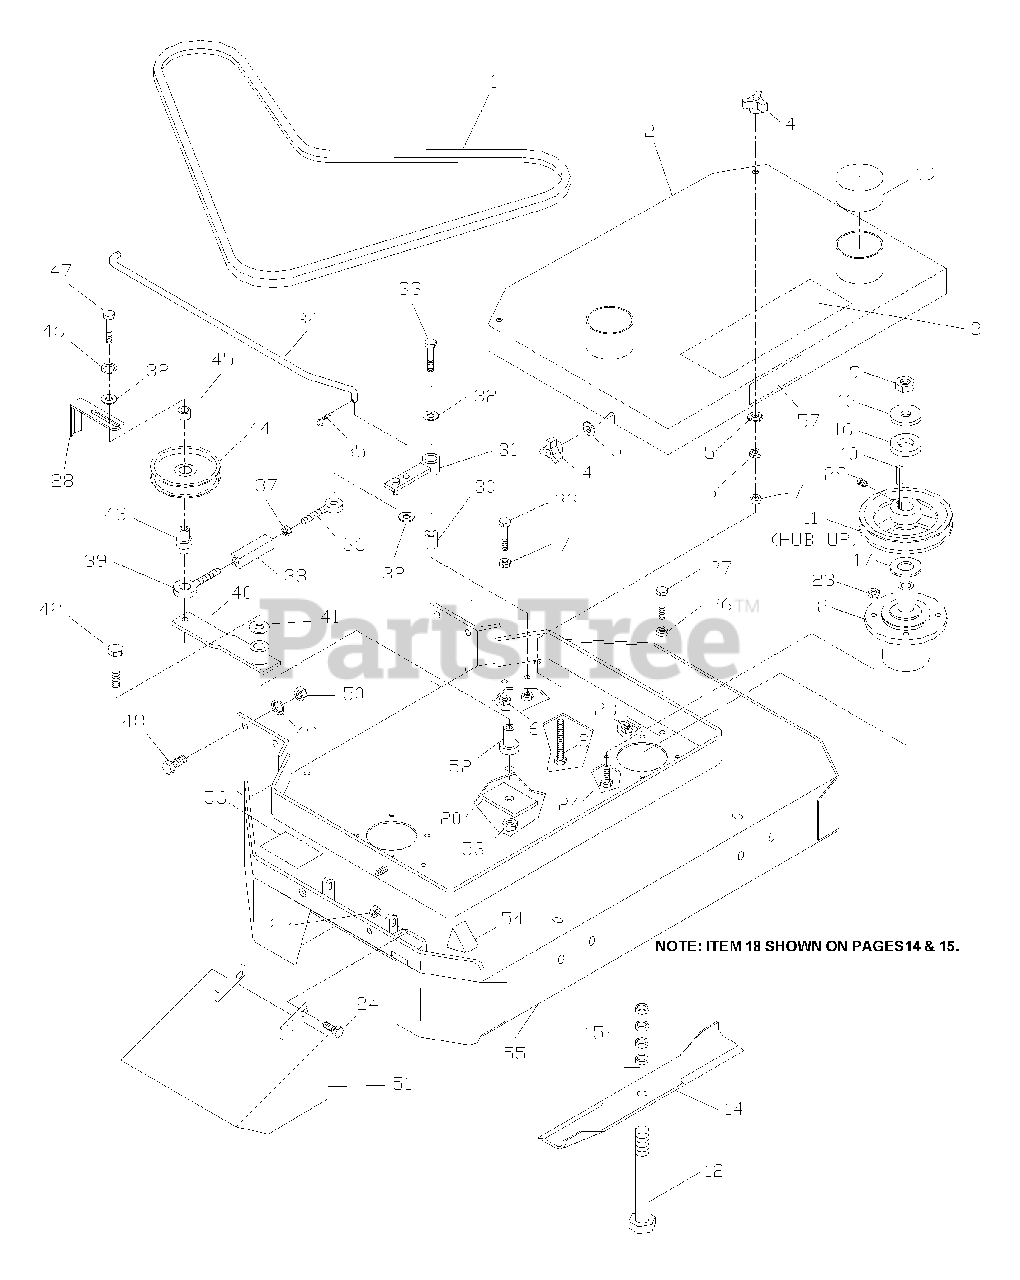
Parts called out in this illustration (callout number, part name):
1	36" DECK BELT
1	32" DECK BELT
2	36" BELT SHIELD
2	32" BELT SHIELD
3	DECAL, HUSQVARNA
5	3/8 SEALING WASHER
7	3/8C WHIZ NUT
8	TAPBOLT 3/8C X 4 1/2
10	KEY 1/4SQ. X 1 1/8
11	PULLEY W/SETSCRS
12	HCS 5/8F X 8 1/2
13	SUPPORT WASHER
14	BLADE 18"
14	BLADE 16 1/4"
15	BLADE SPACERS
17	MACH. BSHG. 10GA.
18	HOUSING ASM.
20	PAD
24	HCS 5/16C X 1
26	HFLN 5/16C
27	HCS 5/16C X 3
29	5/16 NYLOC SETSCR.
30	SLEEVE BUSHING
31	ENGAGEMENT ARM
32	FW 3/8 STD
33	HCS 3/8C X 2 1/4
34	BLADE ROD 32 & 36
35	#2 HAIRPIN
36	RT. HAND EYEBOLT
37	5/16C HEX NUT
38	TURNBUCKLE
39	LT. HAND EYEBOLT
41	FW 1/2 STD
42	HCS 1/2C X 2 3/4
43	EYEBOLT PIVOT
44	IDLER PULLEY
46	3/8 LOCK WASHER
47	HCS 3/8C X 2 1/2
48	HCS 7/16C X 1 1/2
49	7/16 LOCK WASHER
50	7/16C HEX NUT
51	DEFLECTOR CHUTE
52	IDLER SPINDLE
53	HLN 1/2C NYLOC
54	DECAL, CPSC
55	36" DECK W/DECALS
55	32" DECK W/DECALS
56	DECAL, DANGER
57	DECAL, NASCAR
